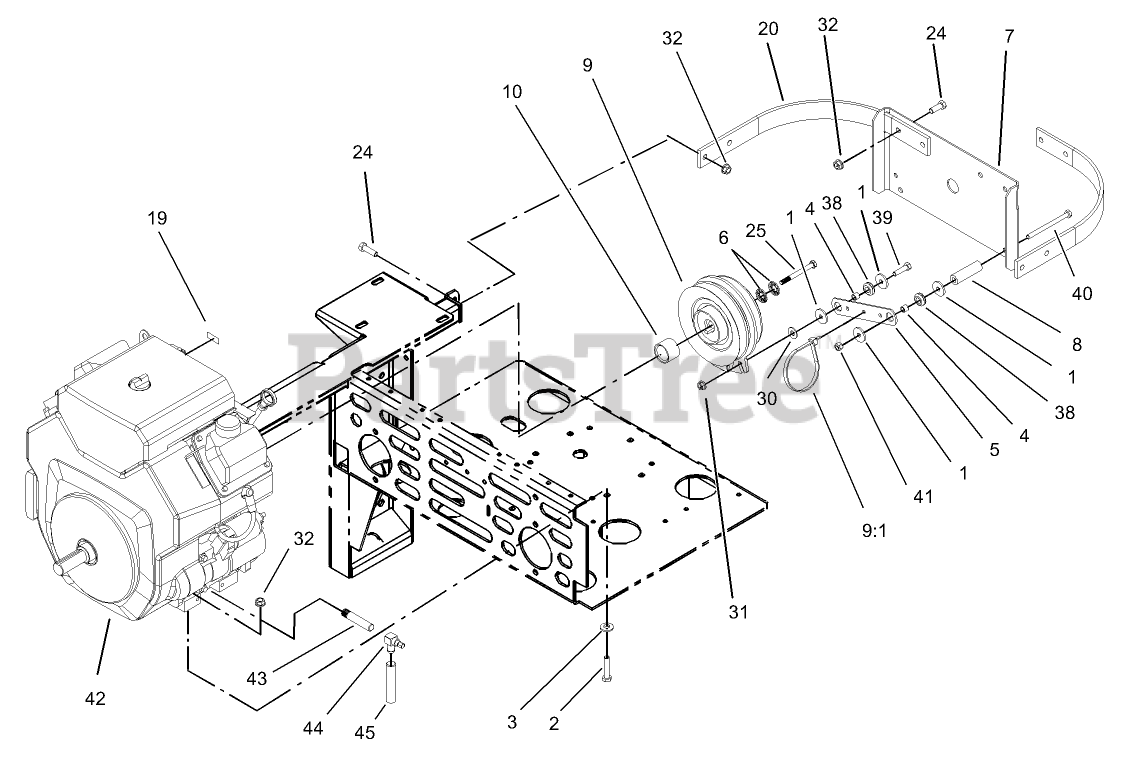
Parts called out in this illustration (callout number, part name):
1	WASHER
2	SCREW-HH
3	WASHER-BELLEVILLE
4	SPACER
5	STRAP-CLUTCH, BRAKE
6	WASHER-SPRING
7	GUARD-CLUTCH
8	SPACER-ANCHOR, CLUTCH
9	Clutch
9:1	TIE-PLASTIC
10	SPACER-CLUTCH
20	BRACKET-GUARD, TOP
24	SCREW-HH
25	SCREW-HH
30	WASHER-FLAT
31	NUT-HF
32	NUT-HHF, WHIZ
38	GROMMET
39	SCREW-HH
40	SCREW-HH
41	NUT-LOCK, NI
43	Adapter
44	Valve-Drain, Oil
45	HOSE-DRAIN, OIL
